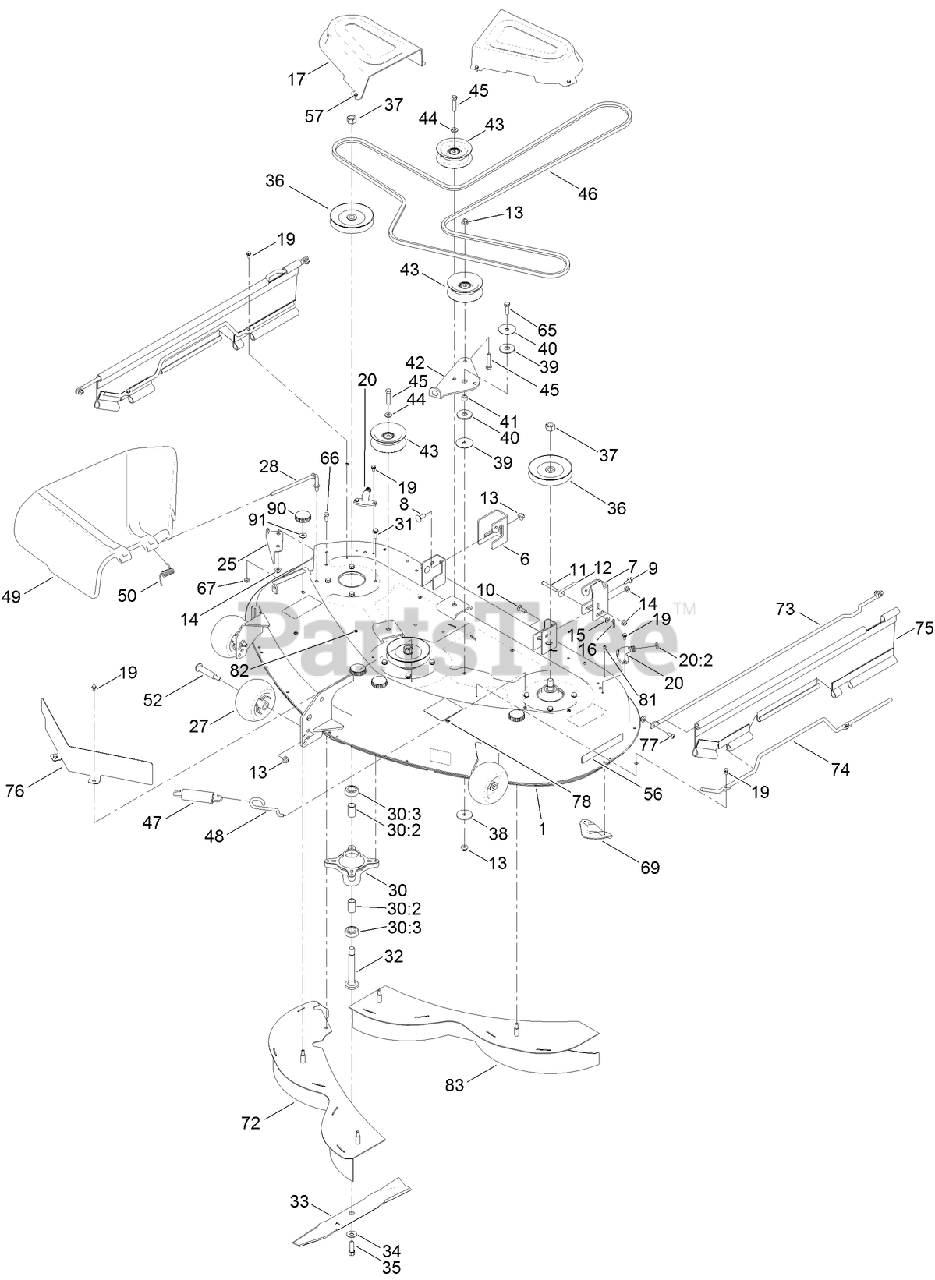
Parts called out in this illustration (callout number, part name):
1	50 INCH DECK AND DECAL ASM
6	BRACKET-HANGER, RH
7	BRACKET-HANGER, LH
8	BOLT-CARR
9	SCREW-SHOULDER,HWH
10	SCREW-CARR
11	PIN-CLEVIS
12	ROD-LEVEL, DECK
13	NUT-HF, NI
14	NUT-HF, NI
15	WASHER-PLAIN
16	PIN-COTTER
17	COVER-BELT
19	SCREW-HWH
20	FITTING-WASHOUT
20:2	O-RING
25	BAFFLE-CUTOFF
27	ROLLER-SCALP, ANTI
28	ROD-PIVOT
30	SPINDLE ASM
30:2	SPACER
30:3	BEARING-BALL
31	SCREW-TAPTITE
32	SHAFT-SPINDLE
33	BLADE-MULCH, 17.50 INCH
34	WASHER-BELLEVILLE
35	SCREW-HH
36	PULLEY
37	NUT-HEX
38	WASHER-REBOUND
39	WASHER
40	WASHER-FRICTION, COMPOSITE
41	SPACER
42	ARM-IDLER
43	PULLEY-IDLER, FLAT
44	WASHER-FLAT
45	SCREW-HH
46	V-BELT
47	SPRING-EXTENSION
48	HOOK-RETURN, SPRING
49	DEFLECTOR
50	SPRING-TORSION
52	BOLT-SHOULDER
56	DECAL-RECYCLER
57	SCREW-TAPTITE
65	SCREW-HH
66	SCREW-HH
69	PLATE-KICKER
72	RH BAFFLE ASM
73	ROD-SUPPORT, UPPER
74	ROD SUPPORT, LOWER
75	GUARD-SIDE
76	SHIELD-FRONT
77	SCREW-HSBH
78	NUT-RETAINING
81	SCREW-PPH
82	NUT-RETAINING
83	LH BAFFLE ASM
91	WASHER-BELLEVILLE
